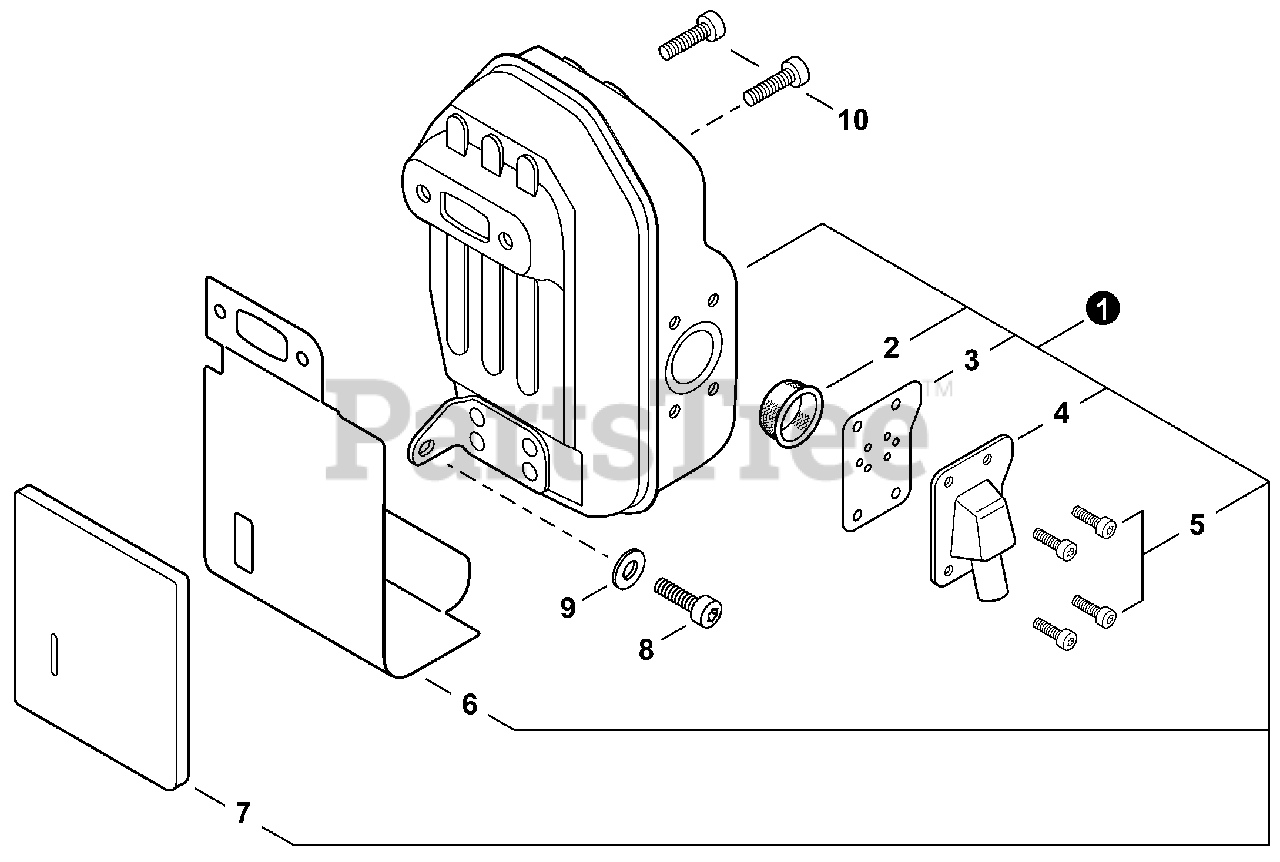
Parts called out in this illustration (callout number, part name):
1	MUFFLER ASSY
2	SCREEN, SPARK ARRESTER
3	GASKET, EXHAUST
4	GUIDE, EXHAUST
5	BOLT, TORX 4×8
6	HEAT SHIELD, EXHAUST
7	INSULATOR, MUFFLER
8	BOLT, TORX 5×16
9	WASHER 5.5×16×2T
10	BOLT, TORX 6×20
